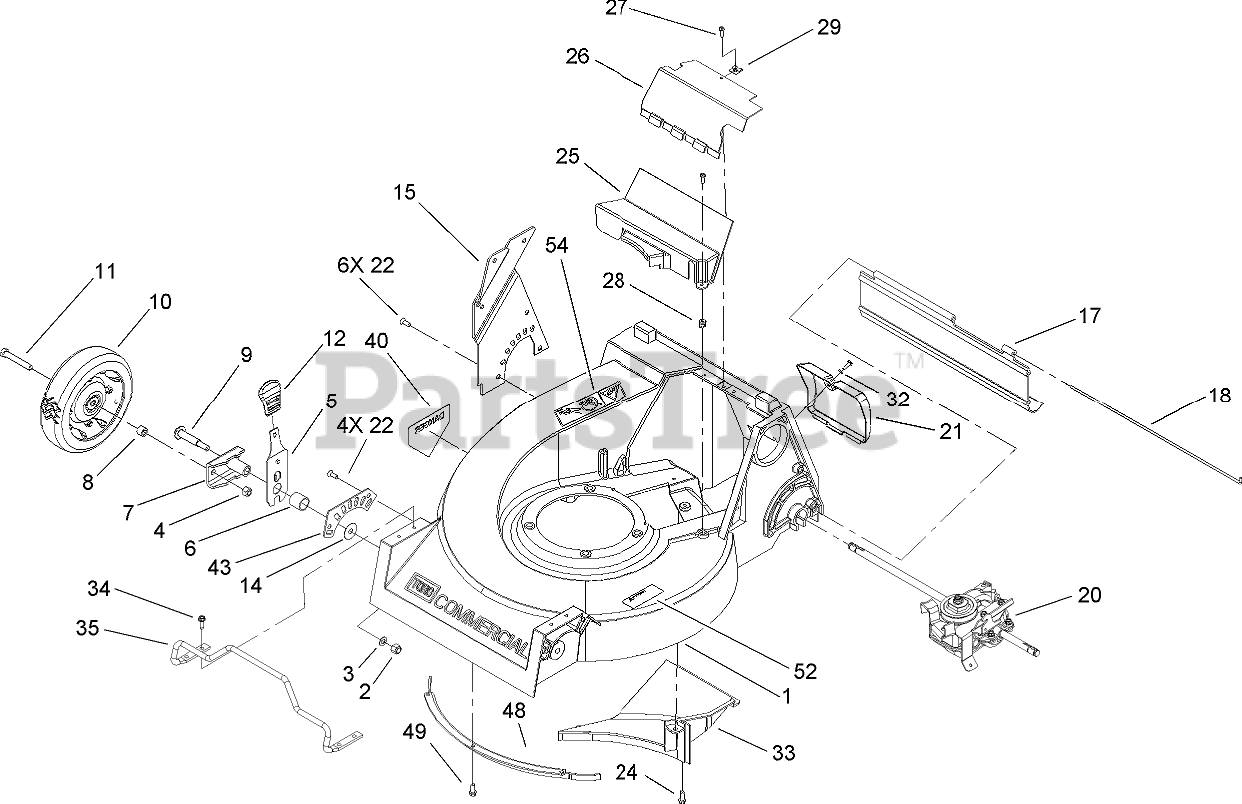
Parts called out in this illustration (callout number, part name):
1	HOUSING
2	NUT-LOCK
3	WASHER
4	NUT-LOCK, CONE
5	SPRING ARM ASM
6	SPACER-BEARING
7	ARM-PIVOT, FRONT
8	SPACER-WHEEL
9	BOLT-WHEEL
10	Wheel and Tire ASM
11	SCREW-HH
12	KNOB-HOC
14	WASHER-PLAIN
15	PLATE-REAR HOC, RH
17	SHEILD-TRAILING
18	ROD-SHIELD
20	GEAR CASE ASM
21	DOOR-ACCESS, REAR
22	SCREW-HH
24	SCREW-HWHTF
25	COVER-BELT, LOWER
26	COVER-BELT, UPPER
28	NUT-CLIP
29	NUT-TYPE J
32	WASHER-FLAT
33	BAFFLE-CHUTE, FLOOR
34	SCREW-HWHTF
35	GUARD-ENGINE
40	DECAL-DANGER
43	PLATE-FRONT HOC, RH
49	SCREW-HWH
52	DECAL-DANGER
54	DECAL-DANGER
